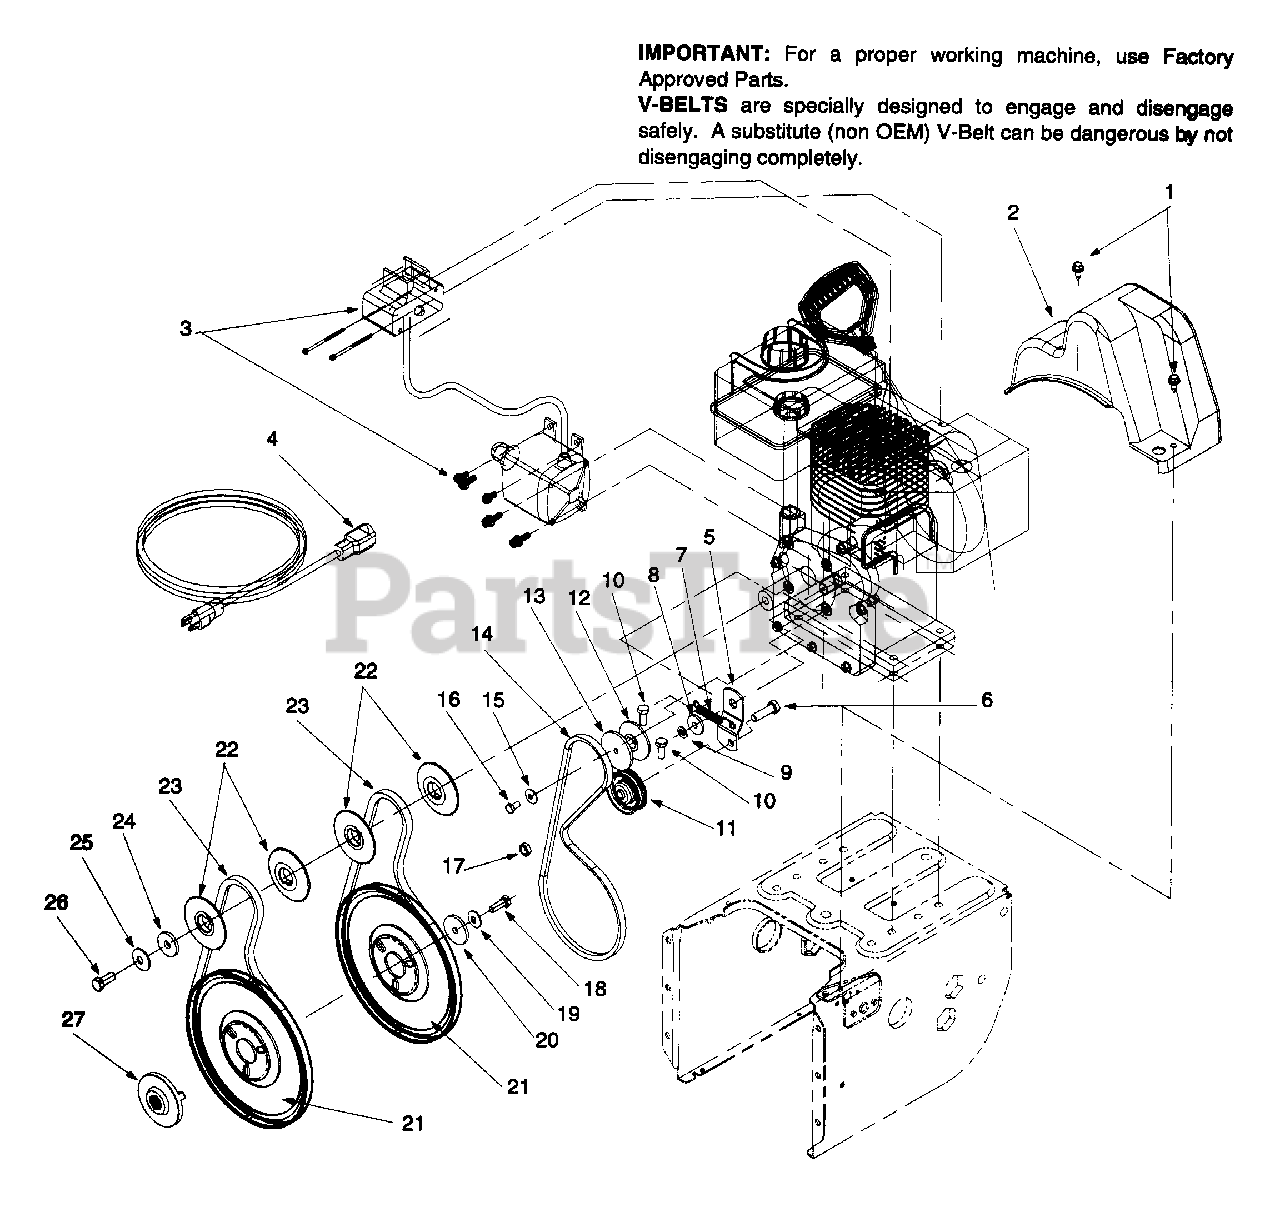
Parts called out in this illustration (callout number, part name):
1	Hex Washer Screw 1/4-14 x .625
2	Belt Cover
3	Electric Start
4	Extension Cord
7	Extension Spring
8	Shoulder Spacer
9	Lock Washer 5/16
10	Lock Hex Cap Screw 5/16-24 x .75
11	Flat Idler
12	Pulley Half
13	Pulley Half
14	V-Belt
15	Bell Washer
16	Hex Cap Screw 1/4-28 x .50
17	Lock Jam Nut 3/8-16
18	Lock Hex Cap Screw 5/16-24 x .87
19	Bell Washer
20	Flat Washer
21	Auger Pulley
22	Pulley Half
23	V-Belt
24	Flat Washer
25	Bell Washer
26	Hex Cap Screw 3/8-24 x .875
27	Adapter Pulley
